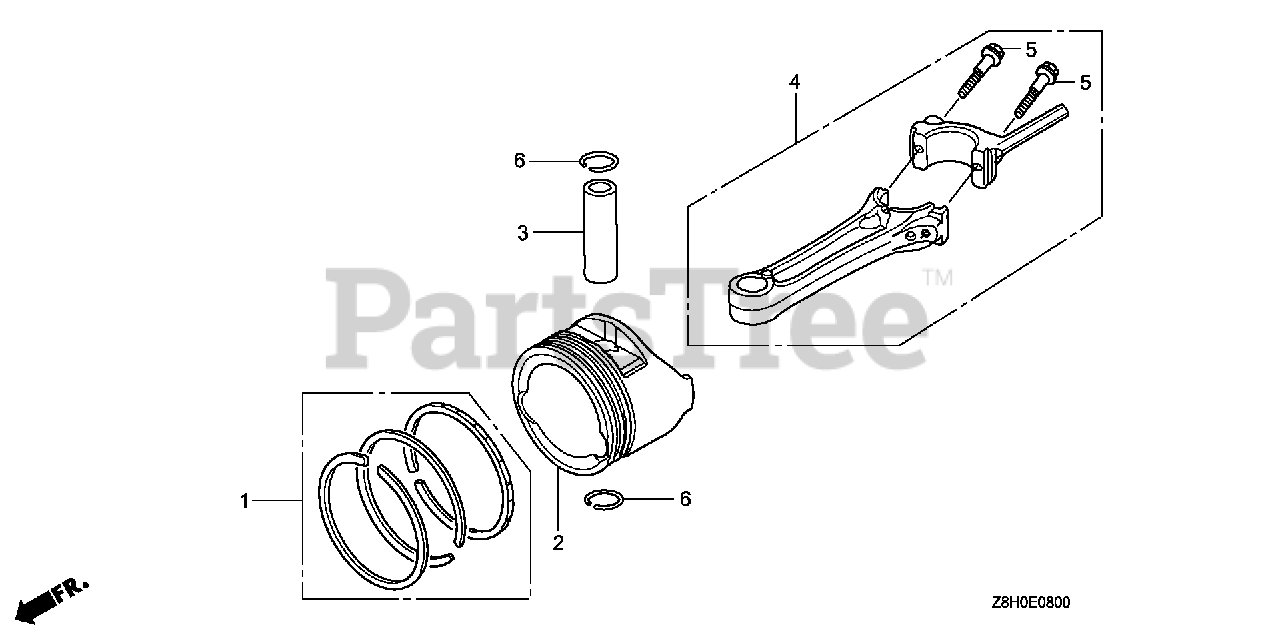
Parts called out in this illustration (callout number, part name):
1	RING SET, PISTON (RIKEN)
1	RING SET, PISTON (TEIKOKU)
3	PIN, PISTON
4	ROD ASSY., CONNECTING
5	BOLT, CONNECTING ROD
6	CLIP, PISTON PIN (13MM)
